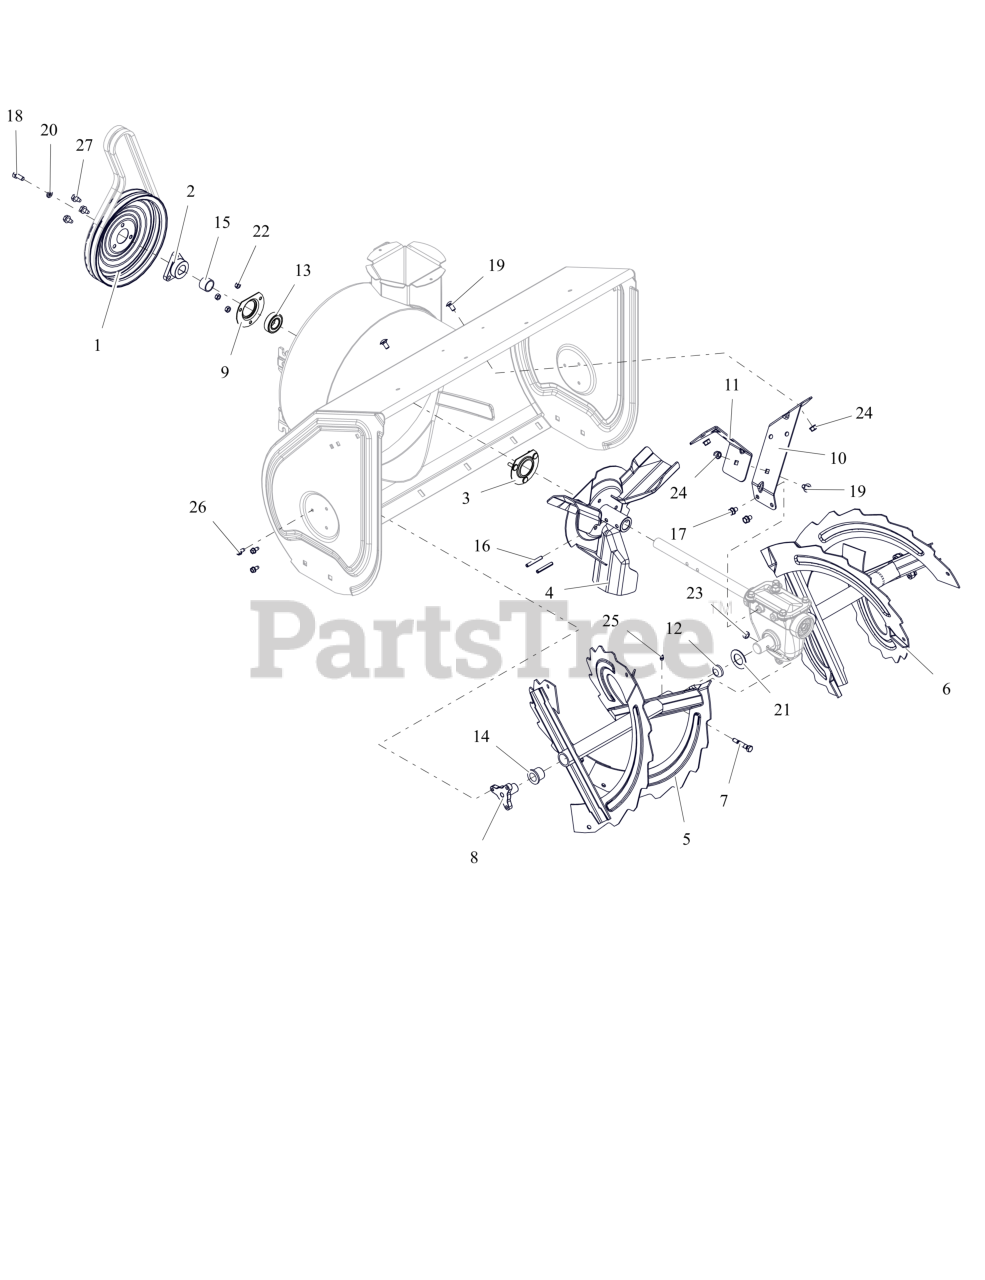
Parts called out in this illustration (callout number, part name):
1	PULLEY, SPIN FORM DUAL GROOVE
2	PULLEY HUB, D-BORE .87 PRO
3	BEARING FLANGE
4	IMPELLER, 3 BLADE-14"
5	RAKE, RH W/ZERK - 30"
6	RAKE, LH W/ZERK - 30"
7	SHEAR BOLT SERVICE ASSEMBLY
8	SUPPORT, RAKE BUSHING
9	BEARING FLANGE
10	BRACKET, GEARCASE SUPPORT - LH
11	BRACKET, GEARCASE SUPPORT - RH
12	PLUG, RAKE TUBE
13	BRG-BALL .876 X 1.750 X .50
14	BSHG-FLG, NY.778 ID X 1.018 OD
15	BSHG,SPCR .895X1.065X.693
16	PIN-ROLL .250X1.75
17	BLT, SEMS .31-18X.50 G5 ZCC
18	BLT, HEX .31-24X.750 G5 ZCC
19	BLT,RHSSN.31-18X.625 G5 ZCCP30
20	WSHR, LK-HVY .312X.097 ZCC
21	WSHR- FLT 1.010X1.755X.062 ZCC
22	NUT,LK-CTR .25-20 GA ZCC
23	NUT,LK-CTR .31-18 GA ZCC
24	NUT-LK-TOP-FLG .312-18 GF ZCC
25	ZERK,FITTING .25X.125 DRIVE IN
26	SCR-TAP .25-20X.50 HWH ZCC
27	SCR,TAP .312-18X.50 HWH TR ZCC
